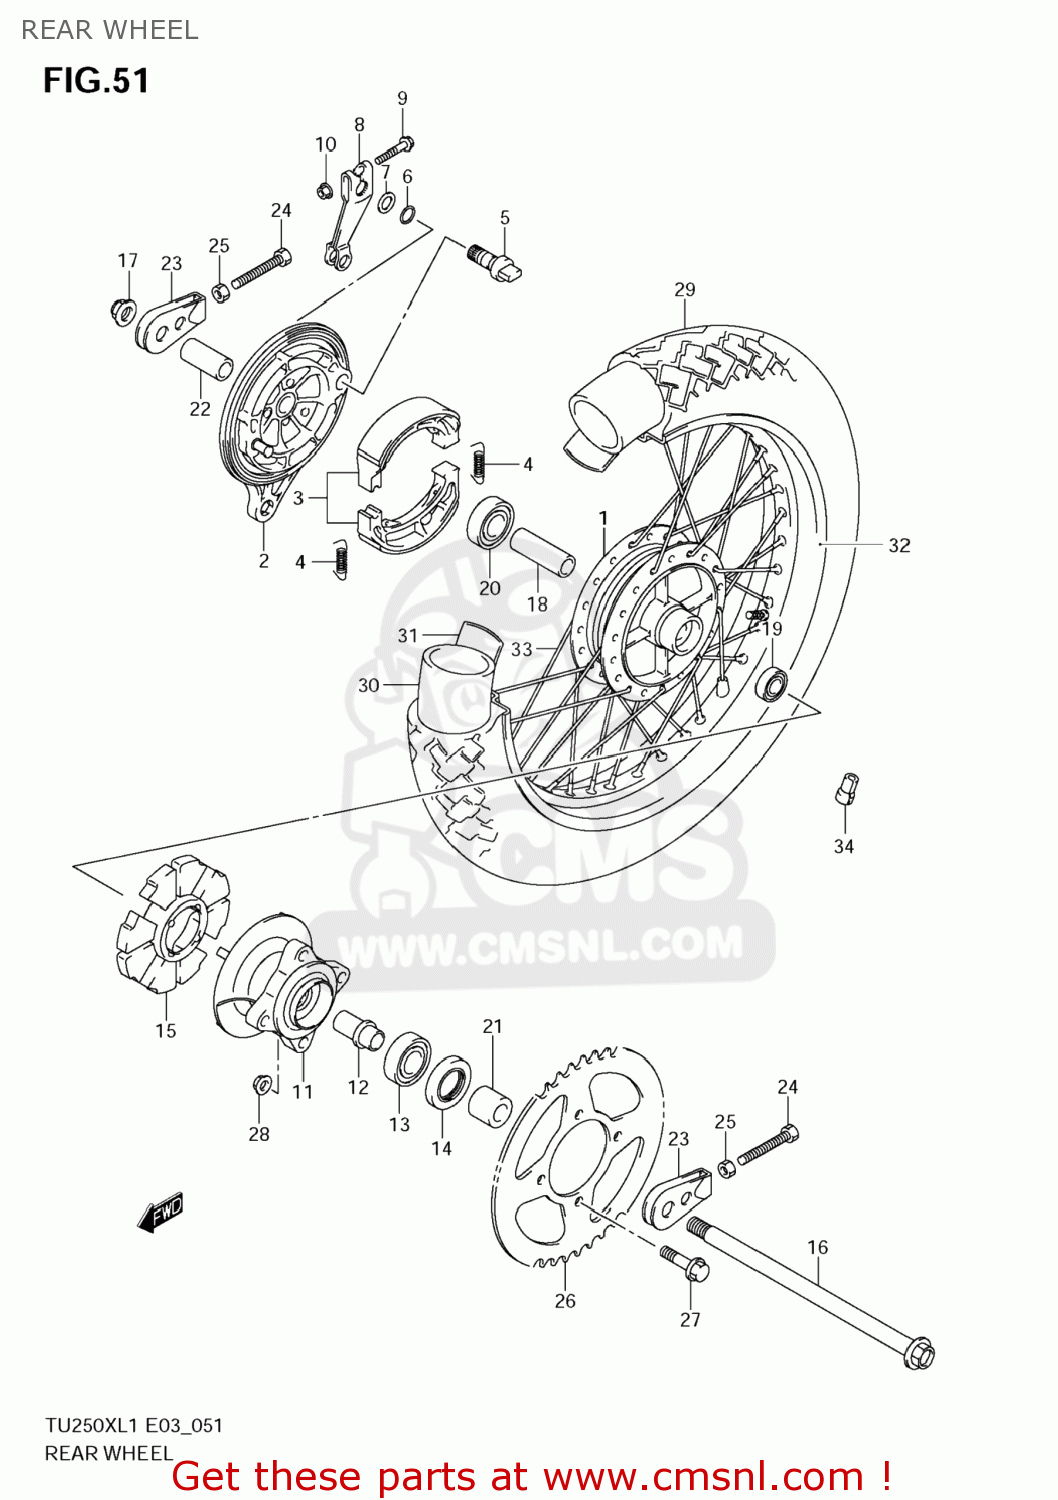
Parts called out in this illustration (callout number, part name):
1	HUB,RR WHEEL
2	PANEL,RR BRAKE ANCHOR
3	SHOE SET,BRAKE (NAS)
4	SPRING(L:34)
5	CAM,BRAKE
6	O RING(D:2.5,ID:13.8)
7	WASHER(14.5X22X1.6)
8	CAM,LEVER
9	BOLT
10	NUT
11	DRUM,RR SPROCKET MOUNTING
12	RETAINER,RR SPROCKET DRUM
13	BEARING(20X47X14)
14	SEAL,OIL(28X47X7)
15	ABSORBER ASSY,HUB SHOCK
16	AXLE,RR
17	NUT
18	SPACER(15.3X21.7X63)
19	BEARING
20	BEARING
21	SPACER(15X28X24.8)
22	SPACER(15X22X46.8)
23	ADJUSTER,CHAIN
24	BOLT(8X50)
25	NUT
26	SPROCKET,RR(NT43-520)
27	BOLT(10X40)
28	NUT
29	TIRE,RR
30	TUBE ASSY,WHEEL INNER
31	PROTECTOR,WHL INR TUBE
32	RIM,RR WHEEL(18M/CXMT2.50)
33	SPOKE SET,RR WHEEL
34	BALANCER,WHEEL(15G)
